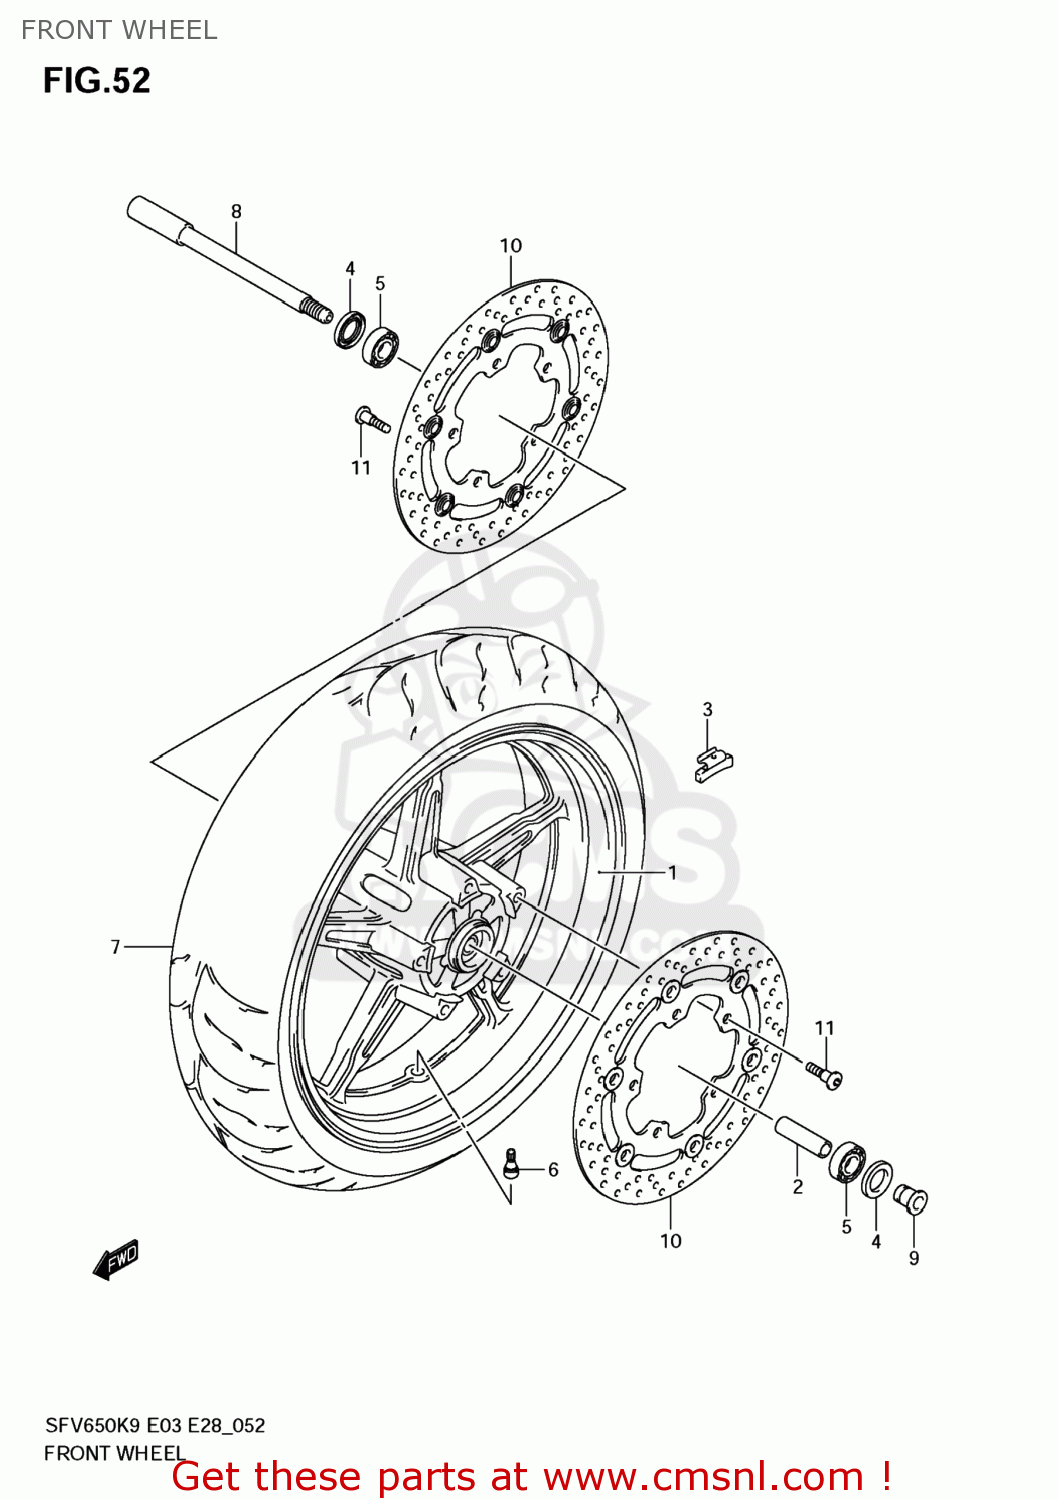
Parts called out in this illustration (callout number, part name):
1	WHEEL,FR(17M/CXMT3.50)
2	SPACER,FR HUB BEARING
3	BALANCER,WHEEL(10G)
4	SEAL,OIL(22X40X7)
5	BEARING
6	VALVE ASSY,WHEEL RIM(TR412)
7	TIRE,FRONT(120
8	AXLE,FR
9	SPACER,FR AXLE,L
10	DISC,FR BRAKE
11	BOLT(8X21)
